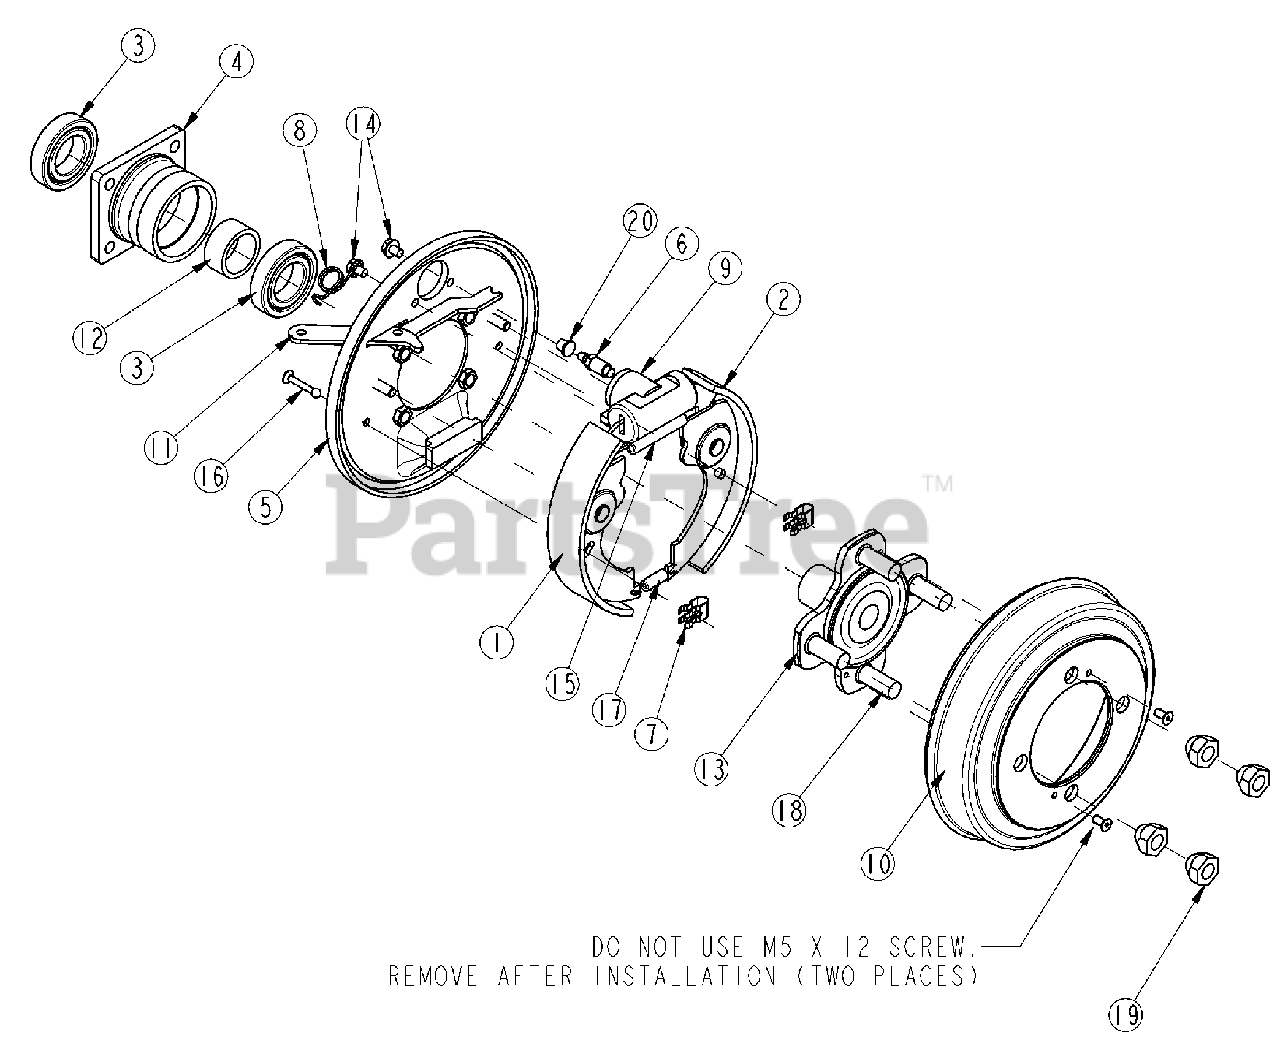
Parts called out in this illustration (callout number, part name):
1	LEFT SHOE
2	RIGHT SHOE
3	BALL BEARING
4	BEARING HOLDER HUB
5	BRAKE SHOE DISC RH
6	BRAKE SHOE DISC LH
7	BLEEDER SCREW
8	SHOES LOCKING SPRING
9	RIGHT SPRING/HAND BRAKE LEVER
10	LEFT SPRING/HAND BRAKE LEVER
11	HYDRAULIC CYLINDER
12	DRUM
13	RIGHT LEVERS SET
14	LEFT LEVERS SET
15	CMX SPACER
16	BRAKE FLANGE HUB W/STUDS
17	SCREW M6 x 40
18	UPPER RETURN SPRING
19	SPRING PIN
20	LOWER RETURN SPRING
